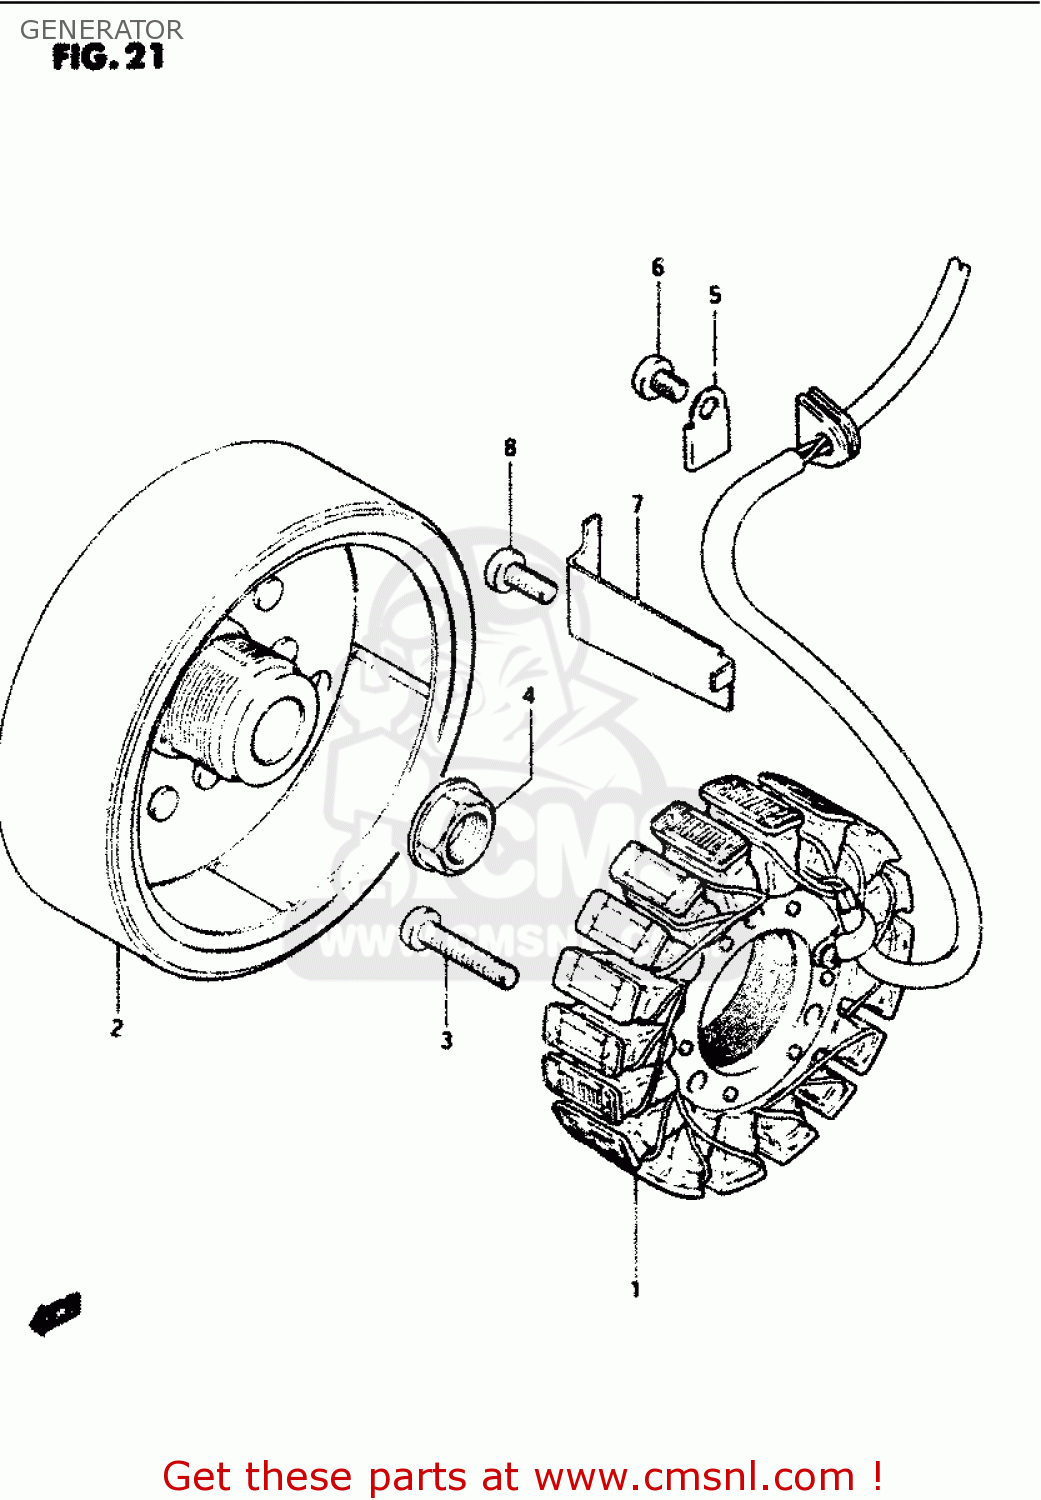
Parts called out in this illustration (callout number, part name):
1	STATOR ASSEMBLY
2	ROTOR ASSEMBLY
3	SCREW 6X30
4	NUT,GENERATOR ROTOR
5	CLAMP,GENERATOR LEAD WIRE
6	SCREW
7	CLAMP,GENERATOR LEAD WIRE
8	SCREW
